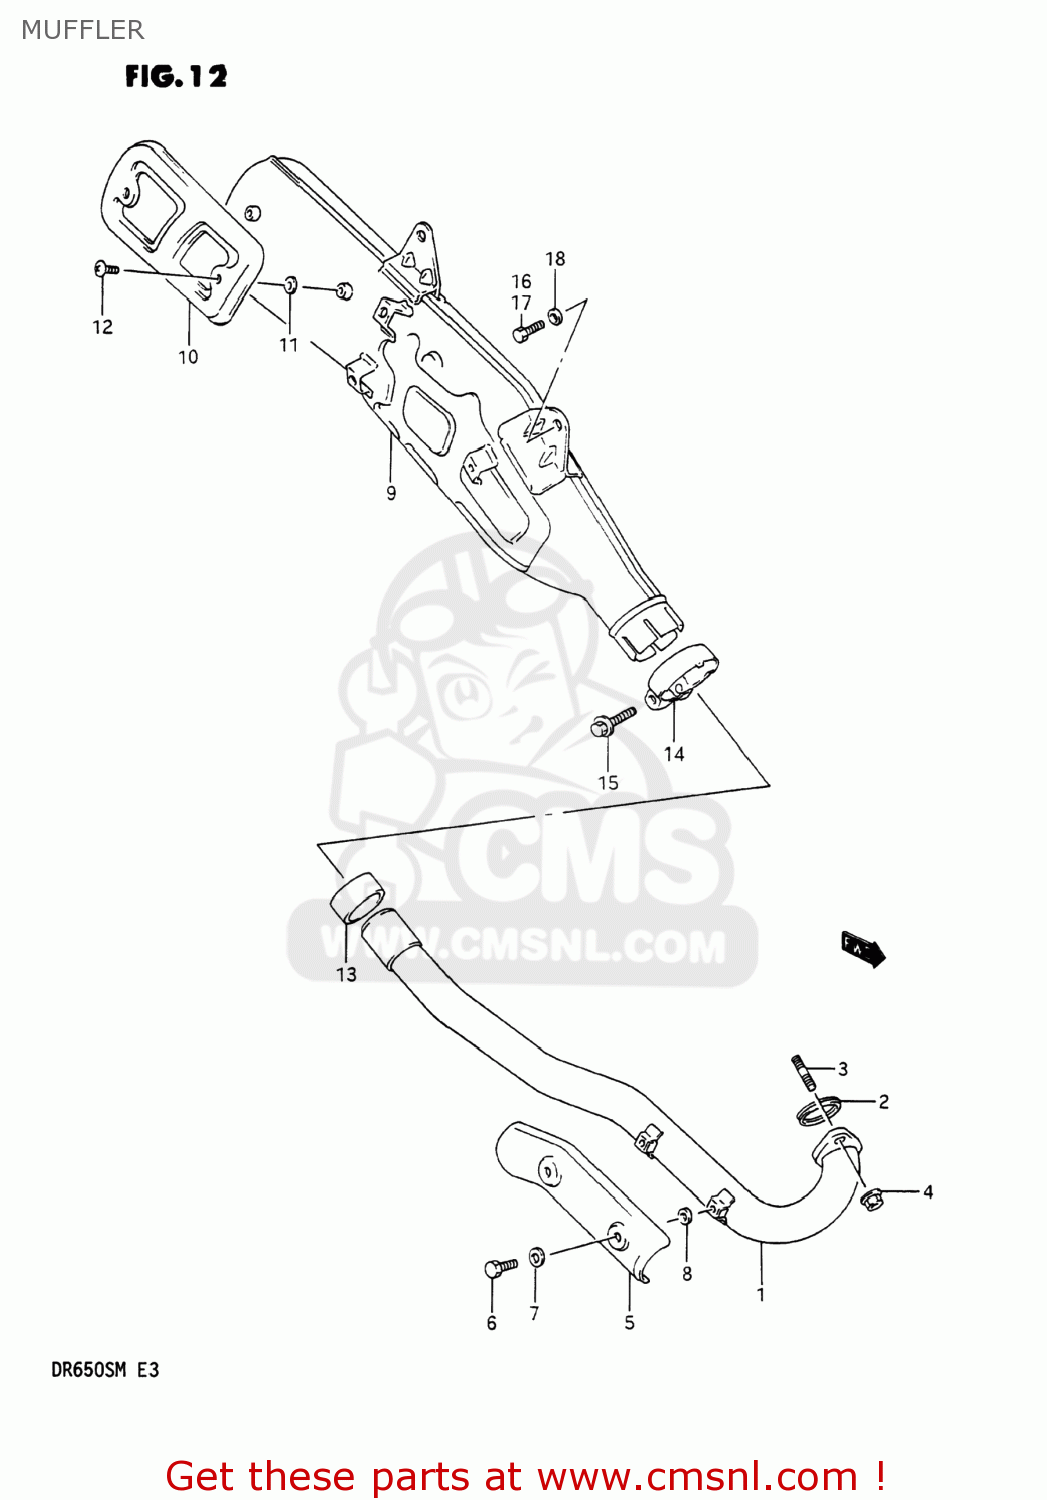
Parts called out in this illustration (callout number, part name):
1	PIPE,EXHAUST
2	GASKET,EXHAUST PIPE (NAS)
3	BOLT,STUD(8X20)
4	NUT M8
5	COVER,EXHAUST PIPE
6	SCREW
7	WASHER(6.5X18X1)
8	GASKET(6X16X1.4) (NAS)
9	BODY,MUFFLER
10	COVER,MUFFLER
11	GASKET,EXHAUST PIPE
12	SCREW
13	CONNECTOR,MUFFLER
14	CLAMP,MUFFLER CONNECTOR LH
15	BOLT 8X40
16	BOLT(8X20)
17	BOLT(8X20)
18	WASHER (8.5X19X2.3)
